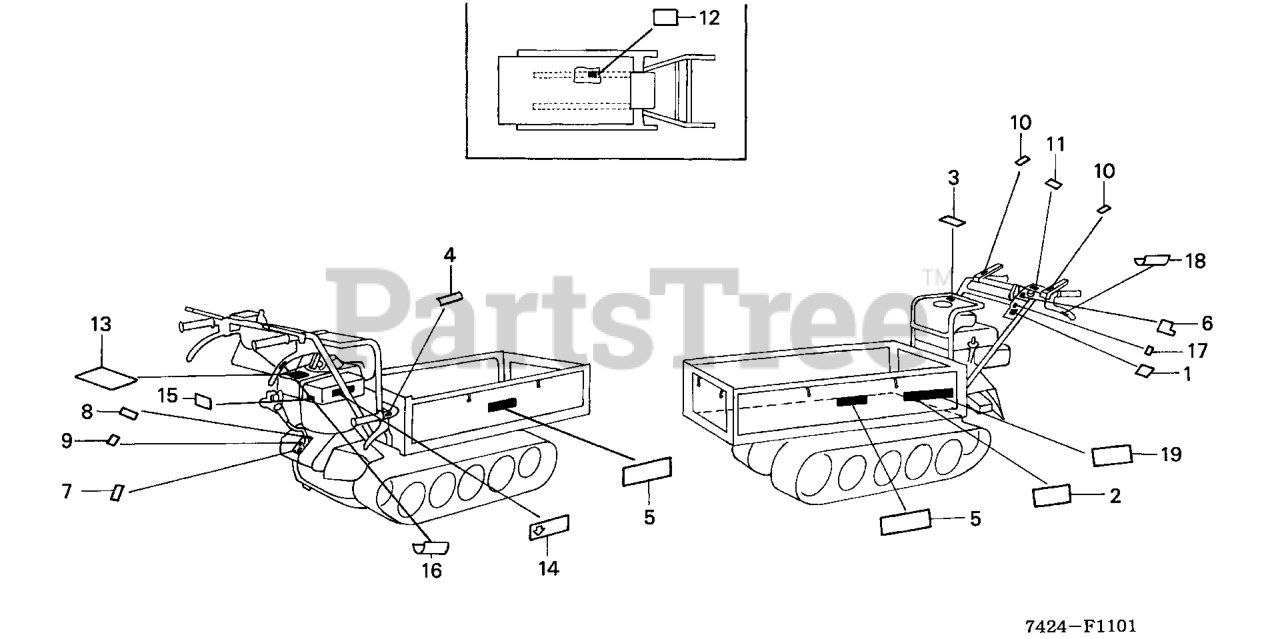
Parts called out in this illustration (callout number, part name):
1	EMBLEM
2	MARK, CARRIER CAUTION (ENGLISH)
3	LABEL, FUEL CAUTION (ENGLISH)
4	MARK, LOCK LEVER
5	MARK, SEAT
6	MARK, ENGINE SWITCH (ENGLISH)
7	MARK, POSITION INDICATION (ENGLISH)
8	MARK, POSITION INDICATION
9	MARK, POSITION INDICATION
10	MARK, CLUTCH INDICATION (ENGLISH)
11	LABEL C, CAUTION
12	MARK, DUMP LOCK
13	LABEL A, CAUTION (ENGLISH)
14	MARK, AIR CLEANER CAUTION (ENGLISH)
15	MARK, CHOKE
16	MARK, R. SIDE CLUTCH (ENGLISH)
17	MARK, THROTTLE
18	MARK, L. SIDE CLUTCH (ENGLISH)
19	LABEL, MAXIMUM WEIGHT CAUTION
